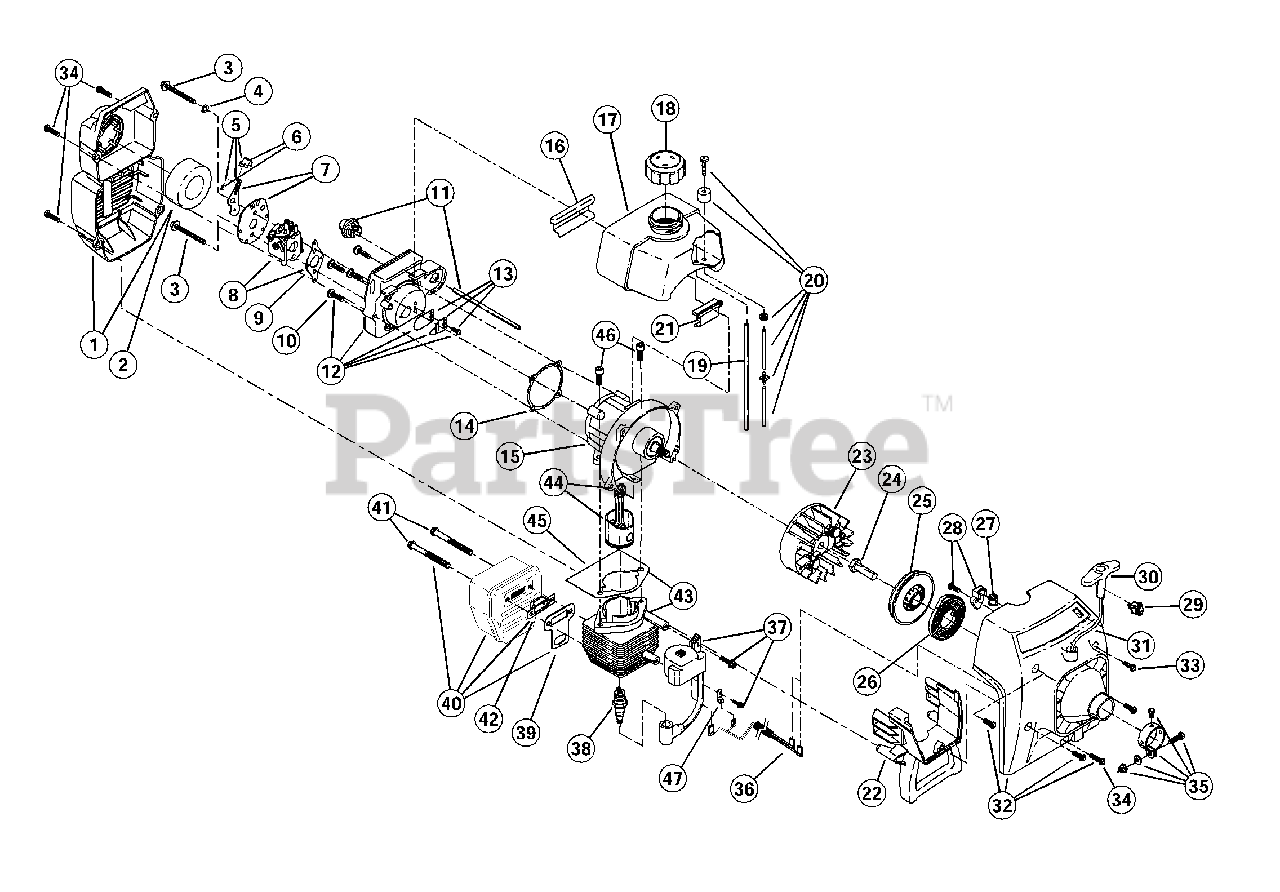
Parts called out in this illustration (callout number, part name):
1	Air Cleaner/Muffler Cover Assembly
2	Air Cleaner Filter
3	Carburetor Mounting Screw Assembly
4	Wavey Washer
5	Choke Lever Assembly
6	Choke Knob and Screw
7	Choke Assembly
8	Carburetor Assembly
9	Carburetor Gasket
10	Carb Mount Screw
11	Primer and Hose Assembly
12	Carb Mount Assembly
13	Reed Assembly
14	Carburetor Mount Gasket
15	Crank Case Service Assembly
16	Rear Mounting Pad
17	Fuel Tank Assembly
18	Fuel Cap Assembly
19	Fuel Return Line
20	Fuel Line Assembly
21	Front Mounting Pad
22	Shroud Extension & Stand
23	Flywheel Assembly
24	Square Nut Drive
25	Recoil Pulley Assembly
26	Recoil Spring
27	Rope Guide
28	Pulley Retainer Assembly
29	Switch Assembly
30	Pull Handle
32	Starter Housing Assembly
33	Screw
35	Upper Clamp Assembly
36	Wire Lead
37	Module Assembly
38	Spark Plug
39	Exhaust Gasket
40	Muffler Assembly
41	Muffler Mounting Bolt Assembly
42	Sparks Arrestor
43	Cylinder Assembly
44	Piston and Rod Assembly
45	Cylinder Gasket
46	Cylinder Bolt
47	Ground Tab
